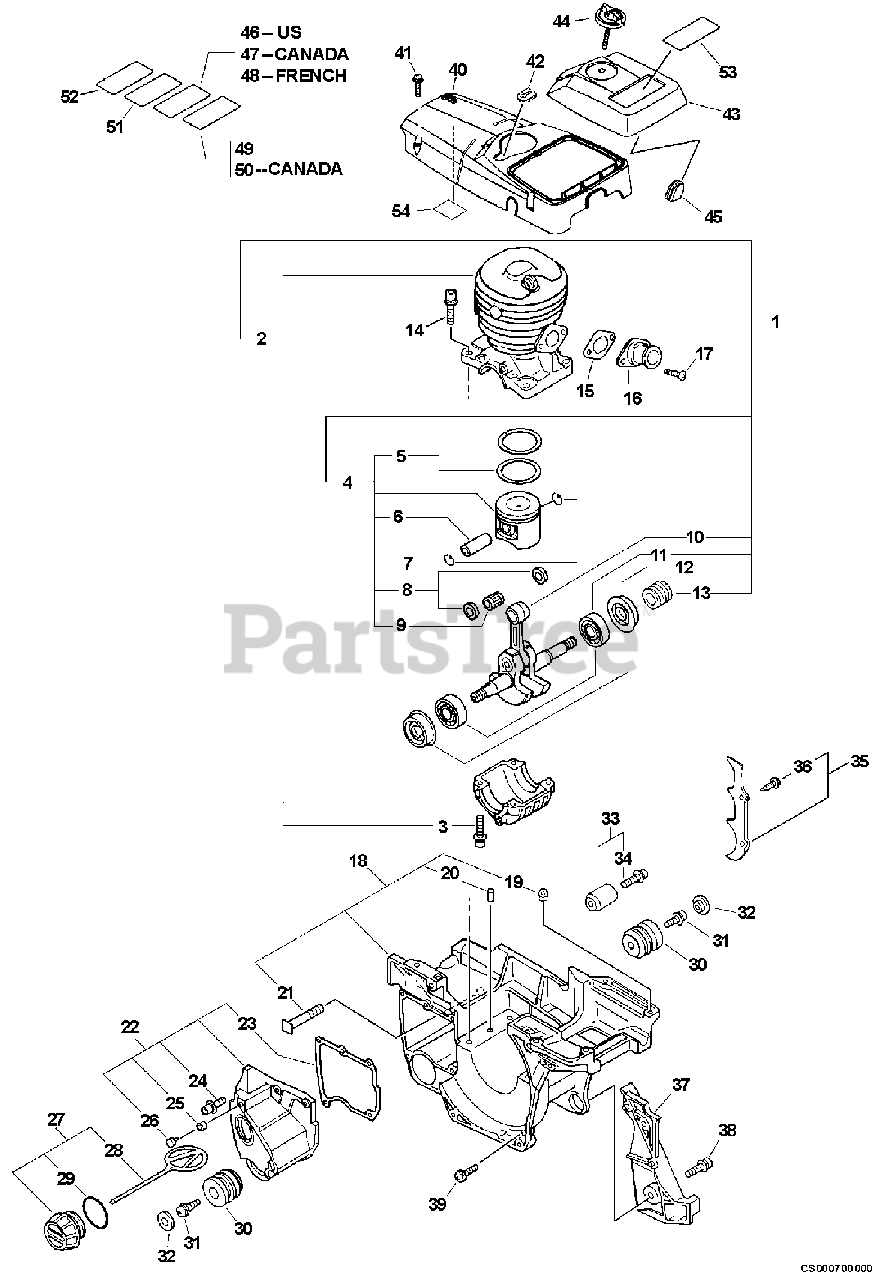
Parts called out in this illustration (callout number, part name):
1	SHORT BLOCK -- SB1080
2	CRANKCASE KIT
3	SCREW - 5X20
4	PISTON KIT
5	RING, PISTON
6	PIN, PISTON
7	RING, RETAINING
9	BEARING, NEEDLE
10	CRANKSHAFT ASSY
11	SEAL, OIL
12	BEARING, BALL - 6202
13	GEAR - WORM
14	SCREW - 5X22
15	GASKET, INTAKE
16	ADAPTOR, INTAKE
17	SCREW - 5X12
18	ENGINE COVER ASSY
20	PIN - LOCATING
21	STUD, GUIDE BAR
22	OIL TANK ASSY
23	GASKET, OIL TANK
24	SCREW - 4X16
26	VENT, TANK
27	CAP ASSY
28	CONNECTOR, CAP
29	O-RING - 25
32	CAP, CUSHION
33	CHAIN CATCHER KIT
34	SCREW - 5X18
35	SPIKE KIT
36	SCREW - 5X12
37	COVER
38	SCREW - 5X16
39	SCREW - 5X16
40	COVER, ENGINE
41	SCREW - 5
42	GROMMET
43	AIR FILTER COVER ASSY - BLACK
44	THUMBSCREW
46	LABEL - KICK BACK
47	LABEL - KICK BACK
48	LABEL - KICK BACK
49	LABEL - BAR & CHAIN
50	LABEL - BAR & CHAIN
51	LABEL - NOISE
52	LABEL - ATTENTION
53	LABEL - MODEL CS-520
54	DEFLECTOR, HEAT
